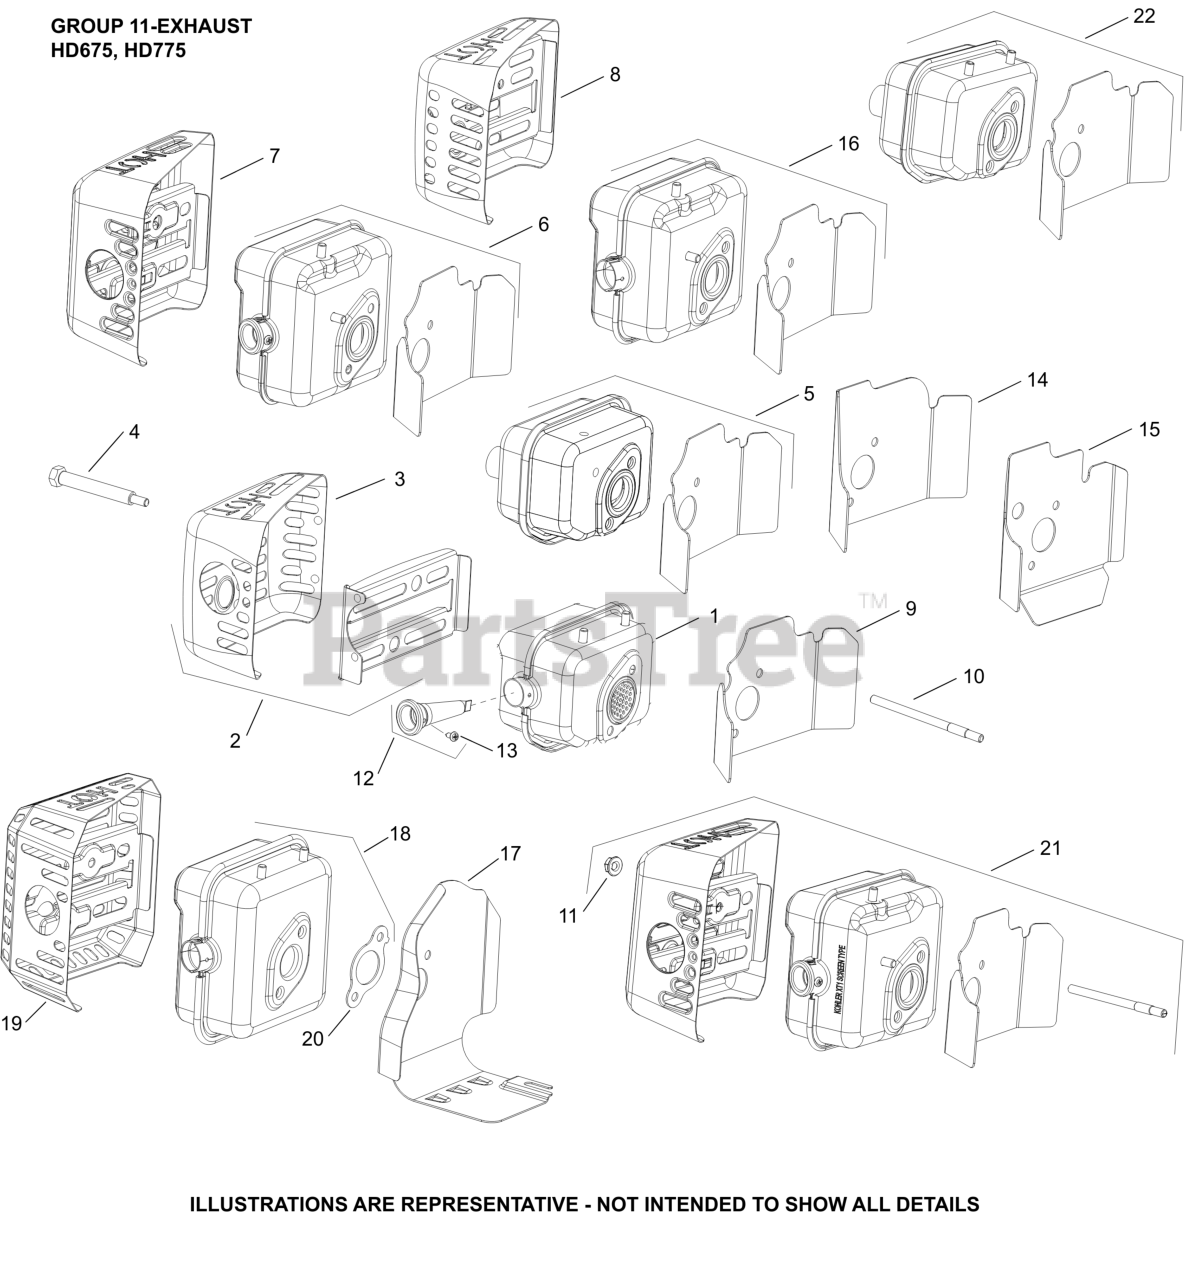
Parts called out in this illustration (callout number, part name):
10	STUD, EXHAUST (M6)
11	NUT, HEX FLANGE LOCK (M6)
18	KIT, MUFFLER
19	GUARD, MUFFLER ASSEMBLY
